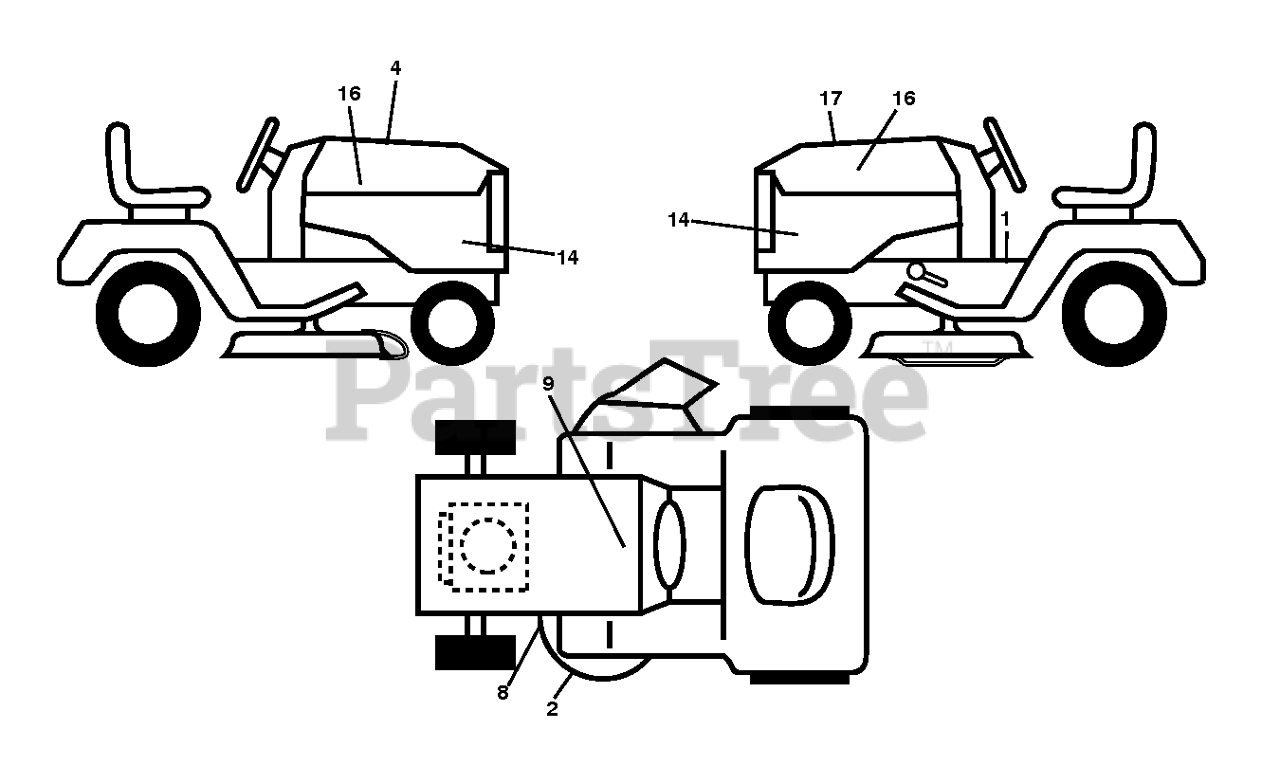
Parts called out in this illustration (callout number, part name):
1	DECAL.FENDER.WARNING
2	DECAL.MOWER
4	DECAL.WARNING.CUST.RESP.E85.
8	DECAL.MOWER.SCH.48/54
9	DECAL BTRY SYMBOLS
14	DECAL.SDPNL.GT2.LGT24K54.422
16	DECAL.BADGE.170MM.TEXTLOGO.
17	DECAL.RPL.KW.FR691V.TGW.54.K46
